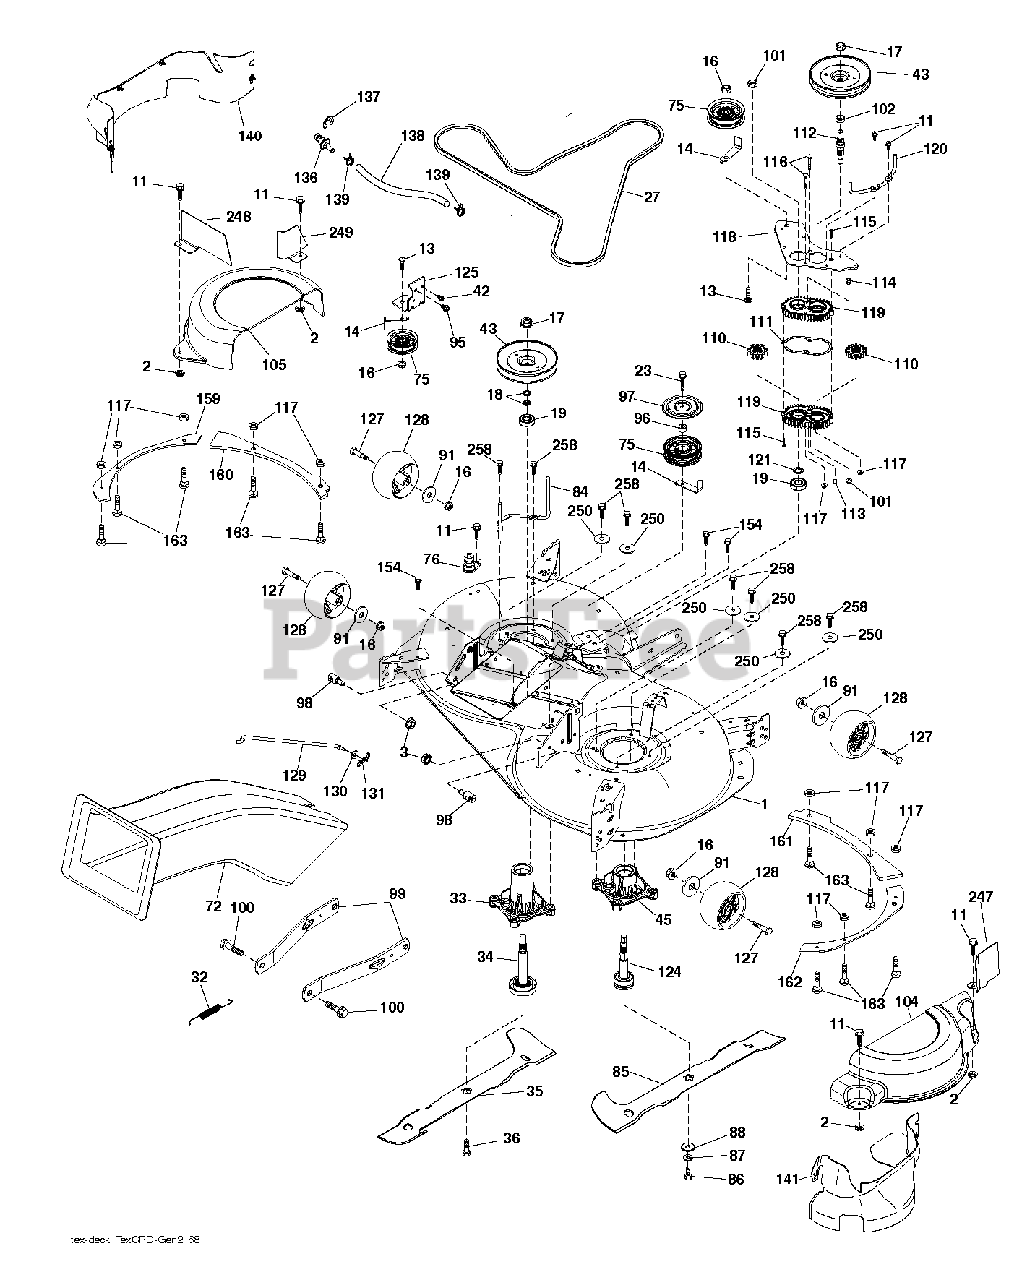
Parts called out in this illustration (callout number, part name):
1	DECK SVC 107HP.EZMUL.498
2	PALNUT 1/4
3	NUT LOCK HEX FLANGE 5/16-18
11	SCREW.1/4-20X5/8
13	BOLT.3/8-16X1.50
14	KEEPER, BELT IDLER
16	NUT LOCK FLG 3/8-16 UNC
17	NUT.FLANGE.LOCK.TOP
18	WASHER.SPACER.MANDREL
23	SCREW LT
27	BELT BELT. ELECTRIC MOWER DRIV
32	SPRING 107CM & 97CM ELECTRIC D
33	HOUSING.MANDREL.REV.TALL.N/GRS
34	SHAFT ASM.REV.TALL.N/GREASEBL
35	BLADE.107.LH.SINGLE.NON.QD
36	BOLT.WASHER.ASM.7/16-2
42	SCREW
43	PULLEY PULLEY MANDREL 5.438 PD
45	RP HOUSING.MANDREL.REV.REVS.
72	RB CHUTE 107/97 TEX GENII
75	FLAT IDLER PULLEY
76	1/2" BARB.DECK.WASHOUT.PORT
84	KEEPER KEEPER. LH MANDREL BELT
85	BLADE.107.RH.SINGLE.NON.QD
86	BOLT.3/8-24X1.25GR8. LHTHRD
87	LOCKWASHER
88	WASHER.BLADE
91	WASHER
95	SCREW, 3/8-16X3/4
96	SPACER
97	PROTECTOR
98	STUD.FASTNER.W/ANTI-ROTATE
99	ARM.SUSPENSION.MOWER.R
100	BOLT.SHOULDER
101	NUT.CROWNLOCK.9/16 -18.UNC
102	SPACER BEARING
104	COVER.MANDREL.107.RH.GEN.2
105	COVER.MANDREL.107.LH.GEN.2
110	GEAR GEAR OUTPUT
111	GASKET GASKET GEARCASE
112	SHAFT SHAFT. CRD GEARCASE ADAP
113	PLUG PLUG OIL
114	VALVE VALVE RELIEF
115	SCREW
116	BOLT.CARIGE.SS.1/4-20X1.75GR5
117	NUT T
118	ARM ARM. CLUTCHING 107 TEX CRD
119	GEARCASE GEARCASE SUBASM
120	KEEPER KEEPER. RH MANDREL BELT
121	WASHER WASHER
124	SUB.ASM.REVERSE.THREAD.REV
125	MANUAL.PARTS.96041018400
127	BOLT.SHOULDER.3/8-16X3-5/8.
128	WHEEL. GUAGE RALLY
129	ROD ROD. SWAY CRD GEN II
130	WASHER
131	PIN.COTTER.5/16.BOW TI
136	PLUG WASHOUT PORT HOOKUP
138	107.WASHOUT.PORT.HOSE (2 2)
139	HOSE.3/8.CLAMP (2 2)
140	GUARD FRENCH 107 TEX ASSEMBLY
141	GUARD SUBASM. 107 TEX GEN 2 RH
154	SCREW T-30 1/4-20 X
159	REINFORCE.PLATE.LHS.BOLT.431
160	REINFORCE.PLATE.LH.FT.X431
161	REINFORCE.PLATE.RH.FRT.X431
162	REINFORCE.PLAT.RH.SD.BLT.X431
163	BOLT
247	GUARD.STEEL.CRD.MANDREL.COV.FR
248	GUARD.STEEL.CRD.MANDREL.COV.FR
249	GUARD.STEEL.CRD.MANDREL.COV.FR
258	BOLT.HEX.WASHR.HED.313-18X1.19
